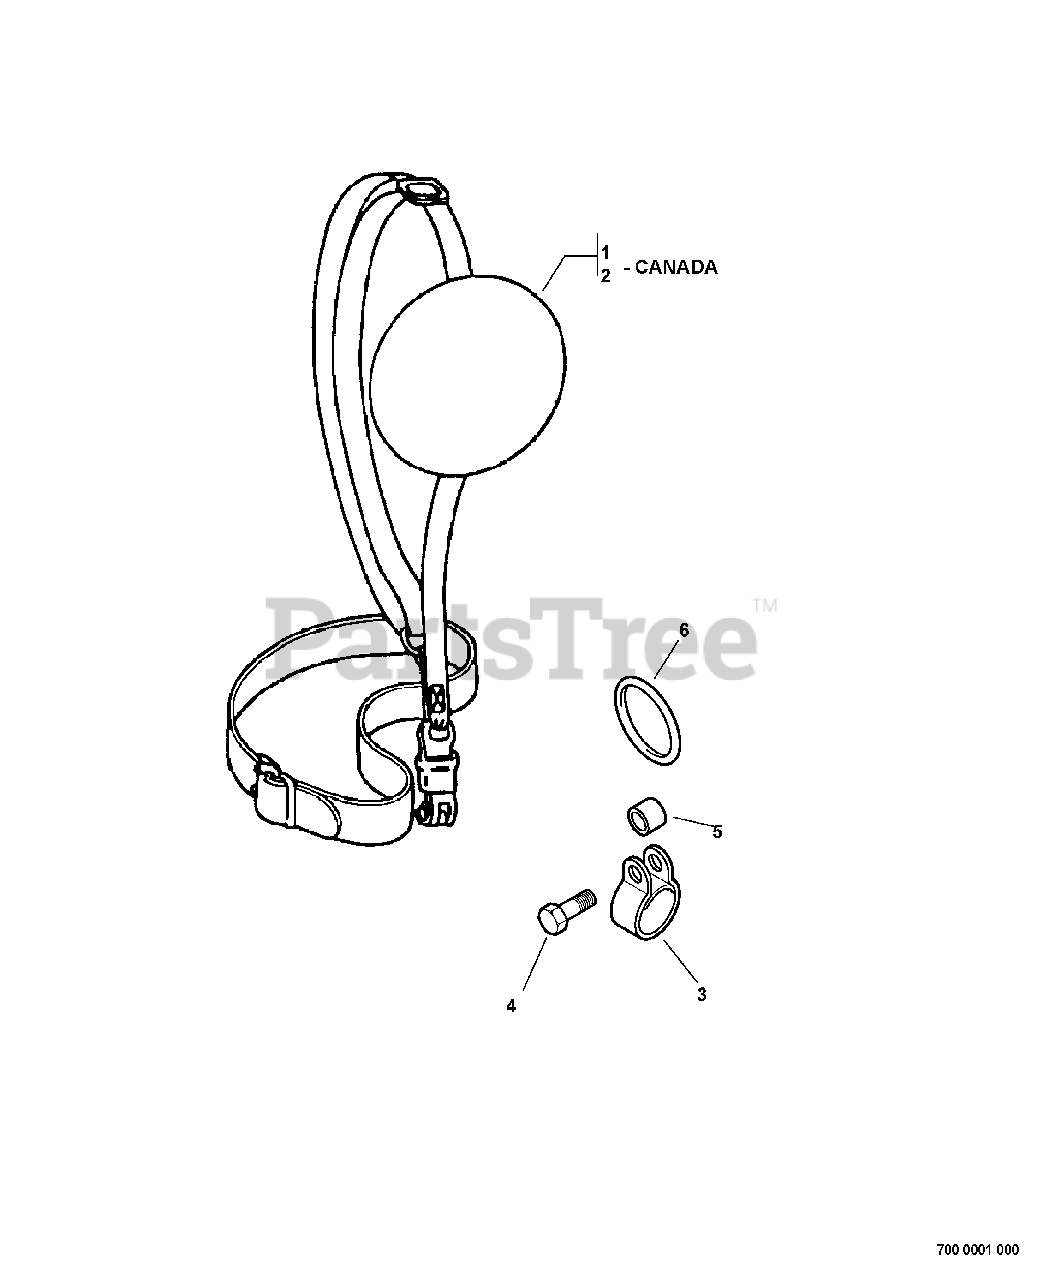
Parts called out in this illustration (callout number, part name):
1	HARNESS ASSY
2	HARNESS ASSY
4	BOLT - 5X18
